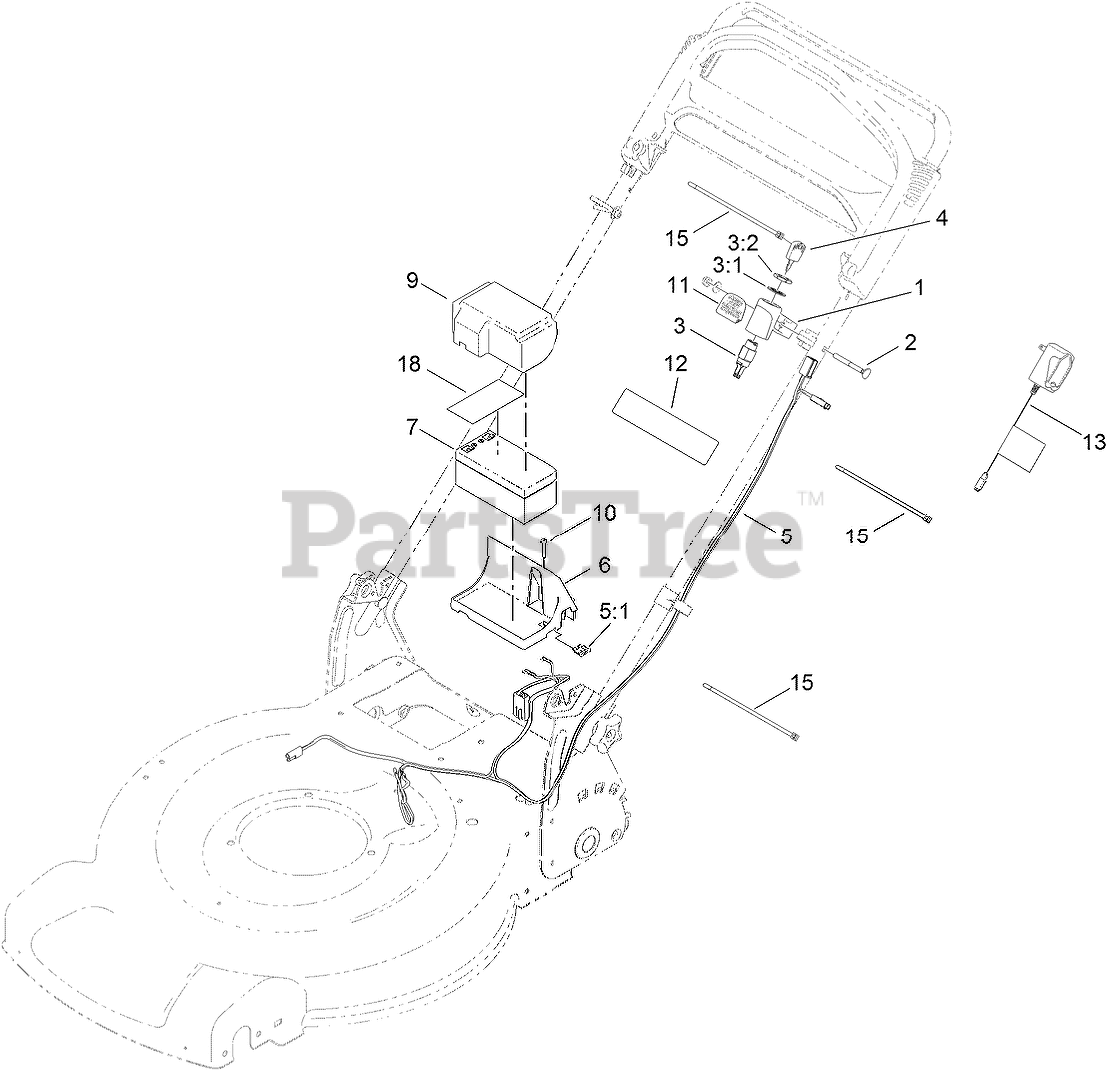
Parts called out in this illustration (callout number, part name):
1	MOUNT-SWITCH
2	SCREW-HANDLE
3	STARTER SWITCH ASM
3:1	WASHER-TOOTH, INTERNAL
3:2	NUT-HH
5	HARNESS-WIRE
5:1	FUSE-40 AMP
6	TRAY-BATTERY
7	BATTERY-WET
9	COVER-BATTERY
10	SCREW-PPH, PLASTITE
11	DECAL-ELECTRIC START
12	DECAL-WARNING
13	CHARGER-CE
15	TIE-CABLE
18	DECAL-TERMINAL, BATTERY
